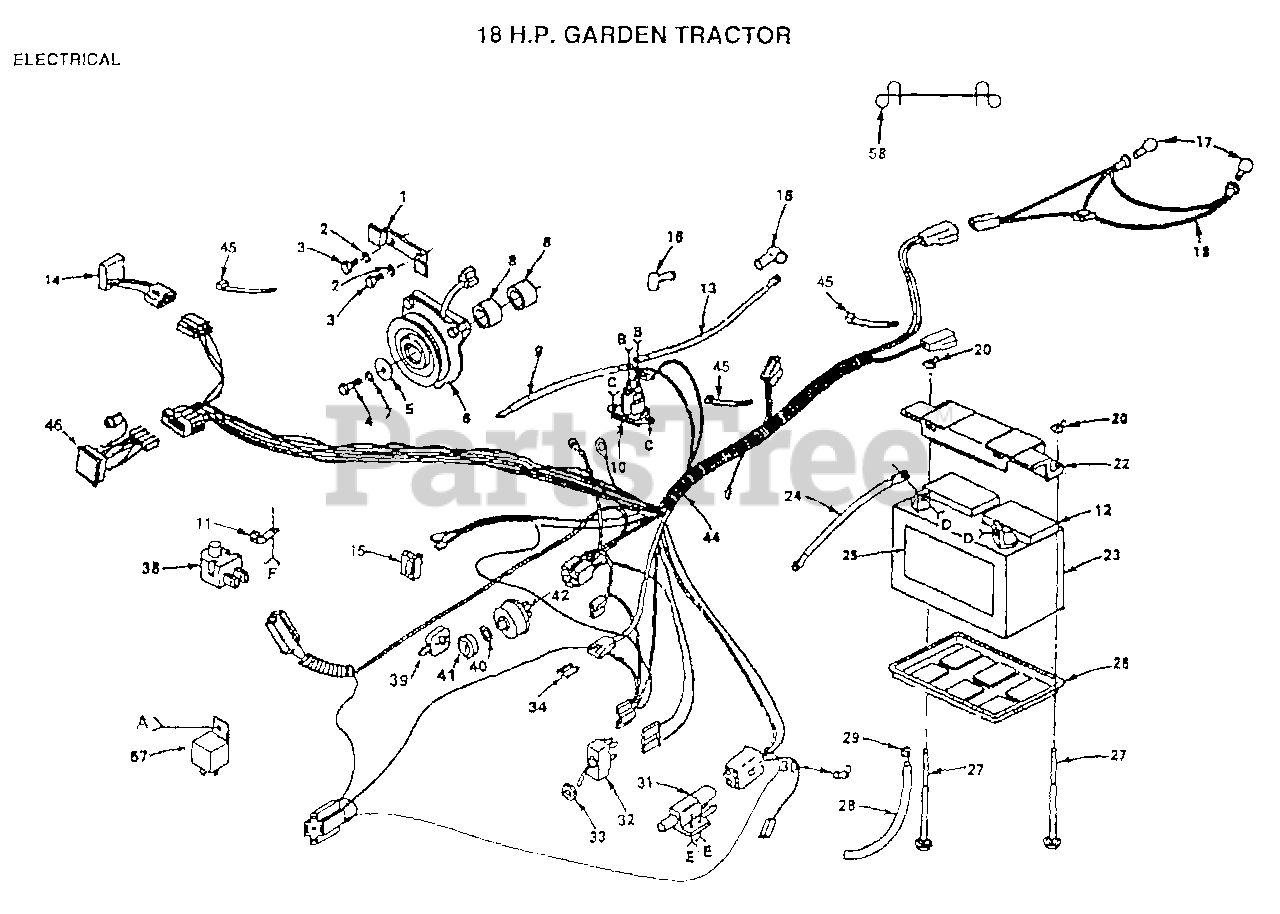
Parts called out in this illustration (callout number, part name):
2	LOCKWASHER
3	BOLT
4	BOLT
5	WASHER T
6	CLUTCH.ELECTRIC.T
7	LOCKWASHER
8	SPACER-CLUTCH GT
9	CABLE-BATTERY T
12	"CAP,BATTERY "
15	SWITCH LT
18	HARNESS T
24	CABLE T
25	DECAL
27	BOLT
29	HOSE CLAMP T
30	CLIP GTV
31	SWITCH INTERLOCKT
32	SWITCH T
33	HEX NUT T
34	FUSE-30 AMP
38	SWITCH SEAT
39	KEY
45	WIRE TIE
46	INDICATORLIGHTT
57	RELAY ASSY T
58	TIE WIRE
